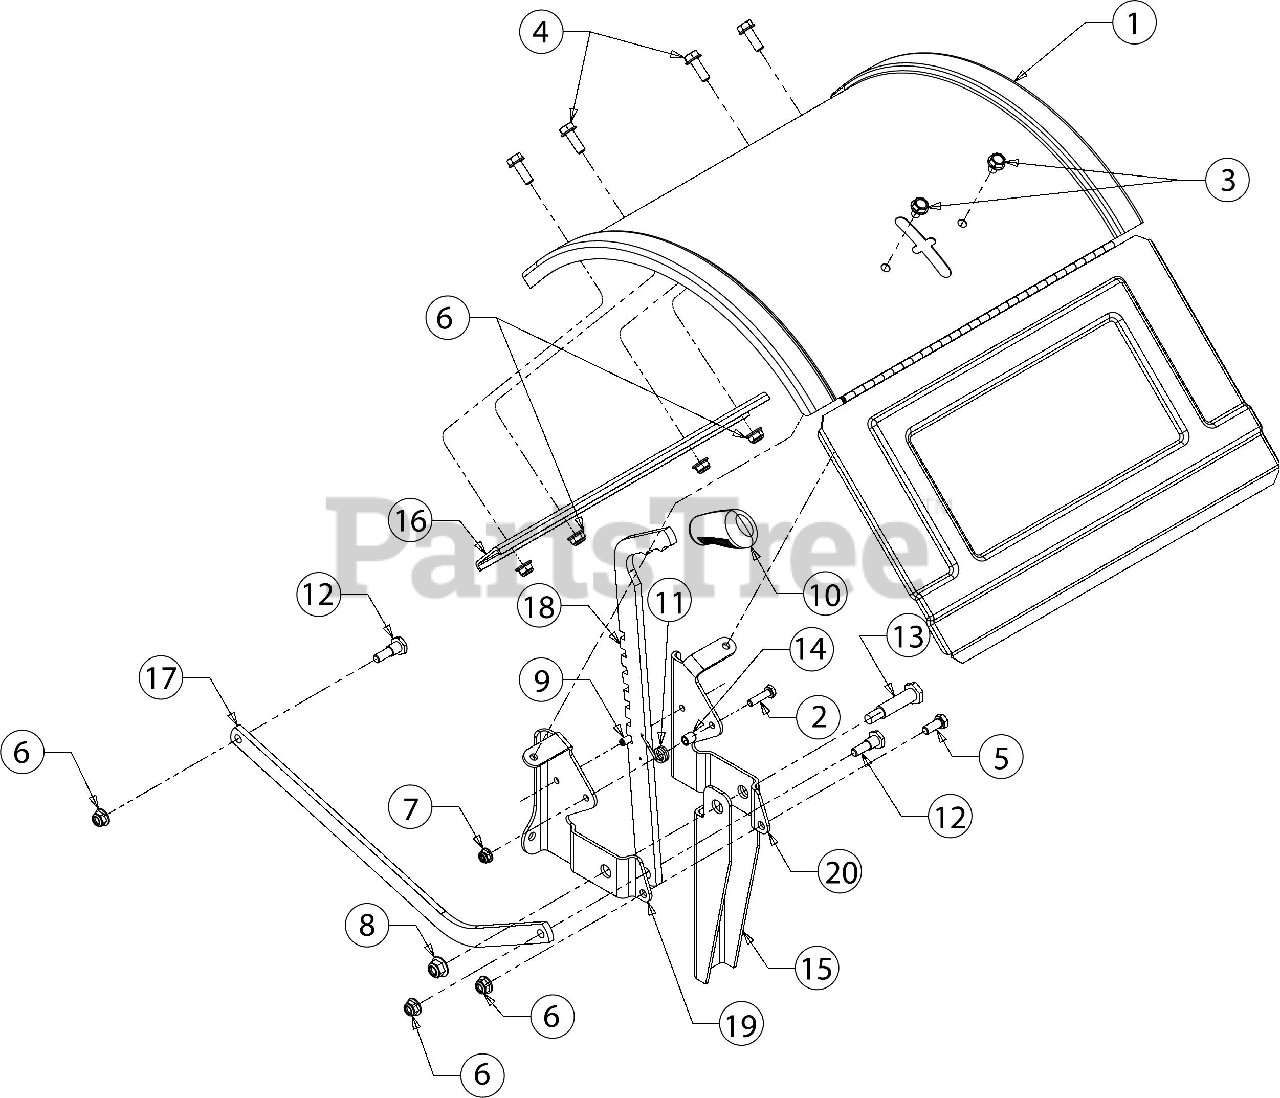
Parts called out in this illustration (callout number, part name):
1	TINE SHIELD ASSEMBLY
2	SCREW 1/4-20 X1.00 GR5
3	SCREW 5/16-18 x .625
4	SCREW 5/16-18 x .875 GR5
5	SCREW 5/16-18 x .75 GR5
6	FLANGE LOCK NUT 5/16-18
7	FLANGE LOCK NUT
9	SPRING PIN 1/4 x 1.00
11	TORSION SPRING
12	SHOULDER SCREW
13	SHOULDER BOLT .498 x 1.635:3/8-16
14	ROUND SPACER
15	REVERSE STOP ARM
16	SUPPORT BRACKET
17	DEPTH DRAG BAR
19	TAIL BRACKET (LH)
20	TAIL BRACKET (RH)
